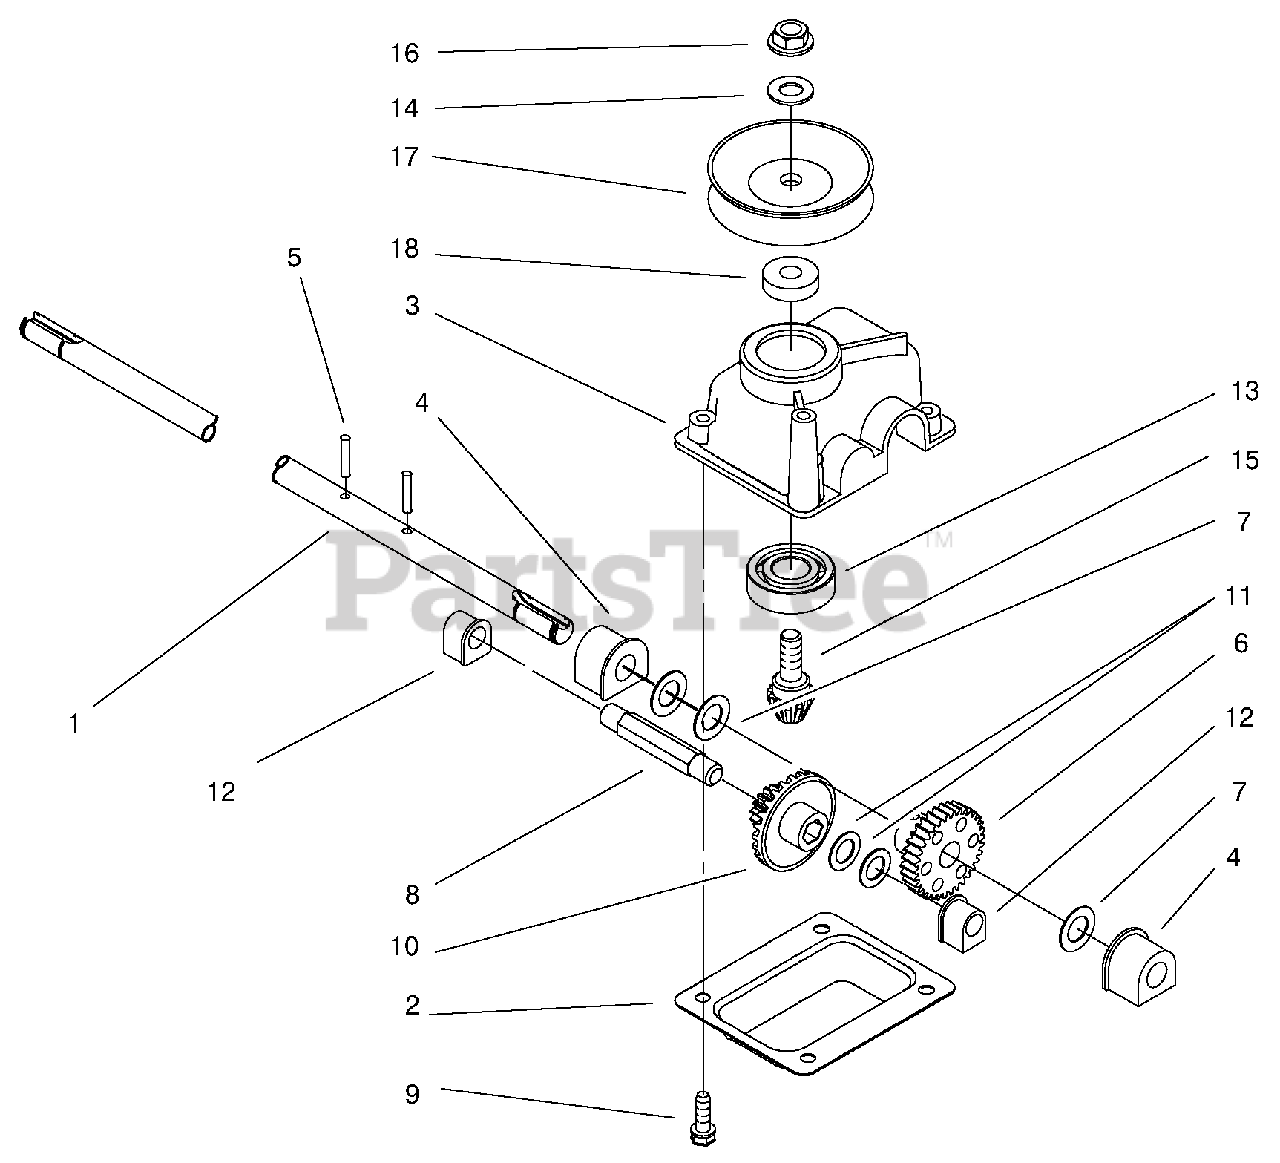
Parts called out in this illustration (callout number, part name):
1	Shaft-Output (only on: 10926)
2	Cover-Gear Case (only on: 10926)
3	Gearcase (only on: 10926)
4	Bushing-Output (only on: 10926)
5	Pin-Groove (only on: 10926)
6	Gear (only on: 10926)
7	Washer (only on: 10926)
8	Shaft-Intermediate (only on: 10926)
9	Screw-Taptite (only on: 10926)
10	Gear-Bevel (only on: 10926)
11	Washer-Thrust (only on: 10926)
12	Bushing (only on: 10926)
13	Bearing-Ball (only on: 10926)
14	Washer-Flat (only on: 10926)
15	Gear-Bevel, Pinion (only on: 10926)
16	Nut-Lock, NI (only on: 10926)
17	Pulley-Half (only on: 10926)
18	Spacer (only on: 10926)
